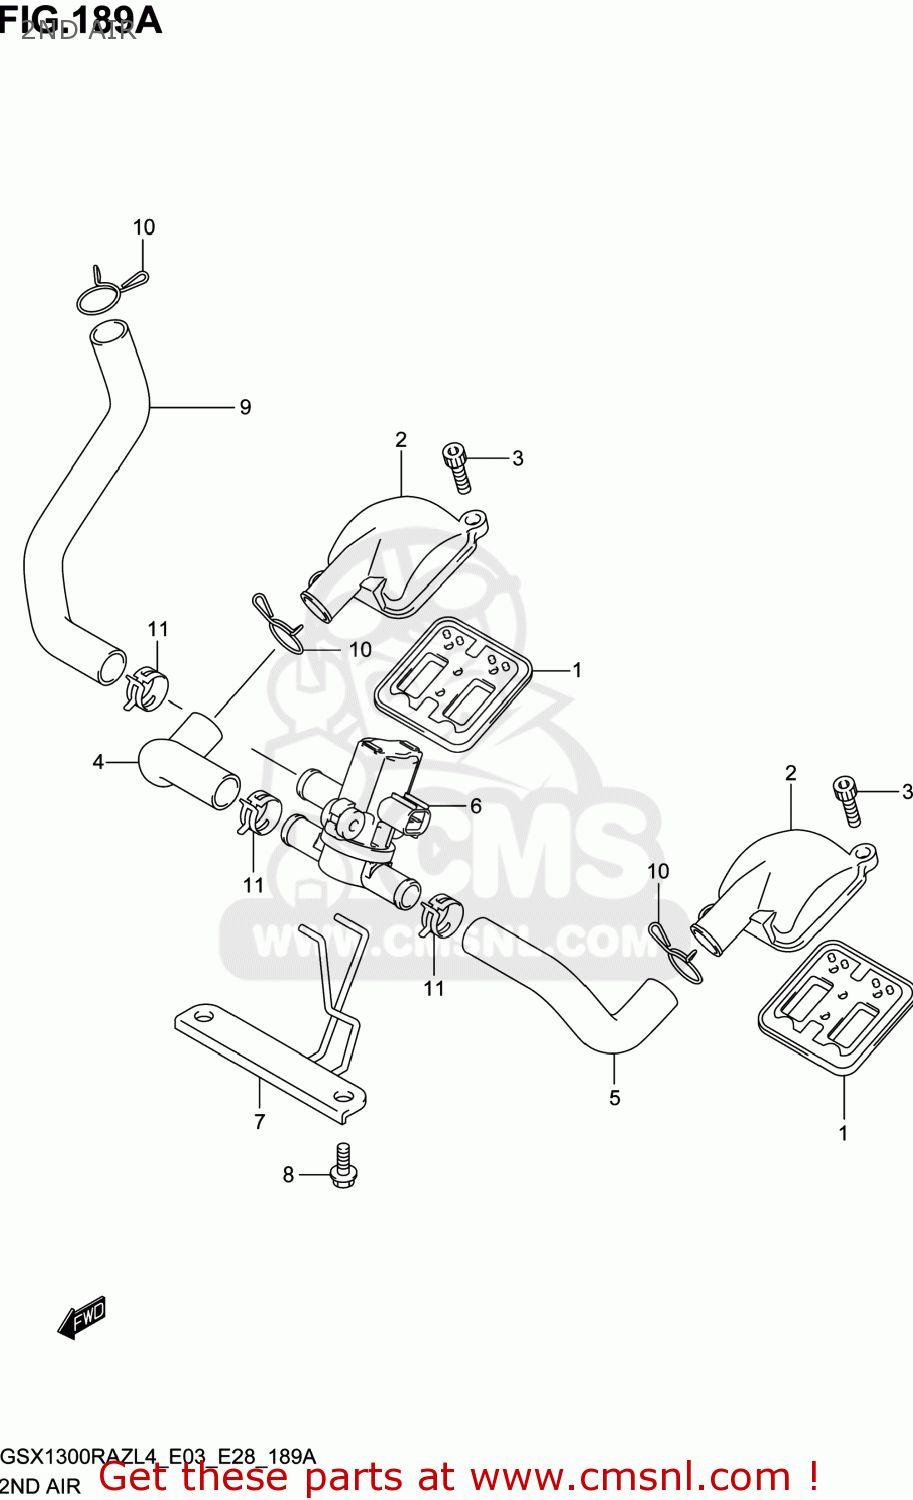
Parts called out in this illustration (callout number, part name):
1	VALVE ASSY,2ND AIR REED
2	COVER,2ND AIR REED VALVE
3	BOLT(6X16)
4	HOSE,2ND AIR VALVE,R
5	HOSE,2ND AIR VALVE,L
6	VALVE ASSY,AIR CUT
7	BRACKET,2ND AIR VALVE
8	BOLT(6X16)
9	HOSE,2ND AIR CLEANER
10	CLIP
11	CLIP
